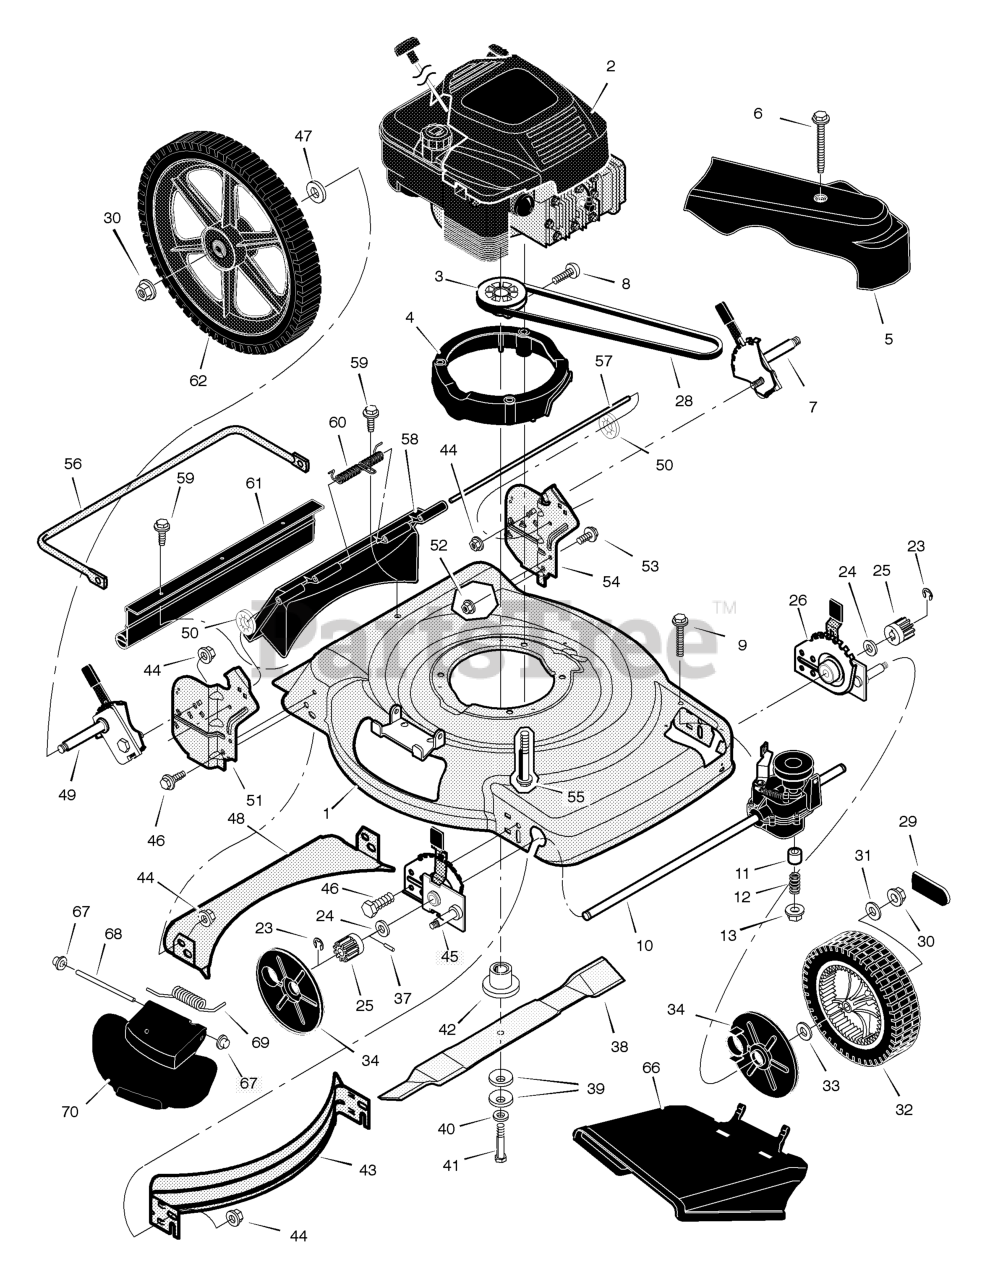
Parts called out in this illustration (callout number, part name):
1	Housing
2	Engine *
3	Pulley, Drive
4	Spacer, Engine
5	Cover, Belt (Gray)
7	Adjuster, Left Rear Height
9	Bolt
10	Transmission *
12	Spring, Compression
13	Nut
25	Gear, Pinion
26	Adjuster, Left Front Height
29	Cap, Hub
30	Nut, Flange
31	Washer
32	Wheel & Tire, Front
34	Cover, Dust
37	Pin, Drive
39	Washer, Belleville
42	Adapter, Blade
43	Baffle, Front
44	Nut, Flange
45	Adjuster, Right Front Height
46	Bolt
48	Baffle, Rear
49	Adjuster, Right Rear Height
50	Retainer, Push
51	Bracket, Right Handle
52	Nut, Flange
53	Bolt
54	Bracket, Left Handle
55	Bolt, Engine
57	Rod, Pivot
58	Door, Rear (Gray)
60	Spring
61	Guard, Rear
62	Wheel & Tire, Rear
66	Deflector, Chute (Gray)
67	Push On Cap
68	Rod, Pivot
69	Spring, Torsion
70	Cover, Mulch (Gray)
